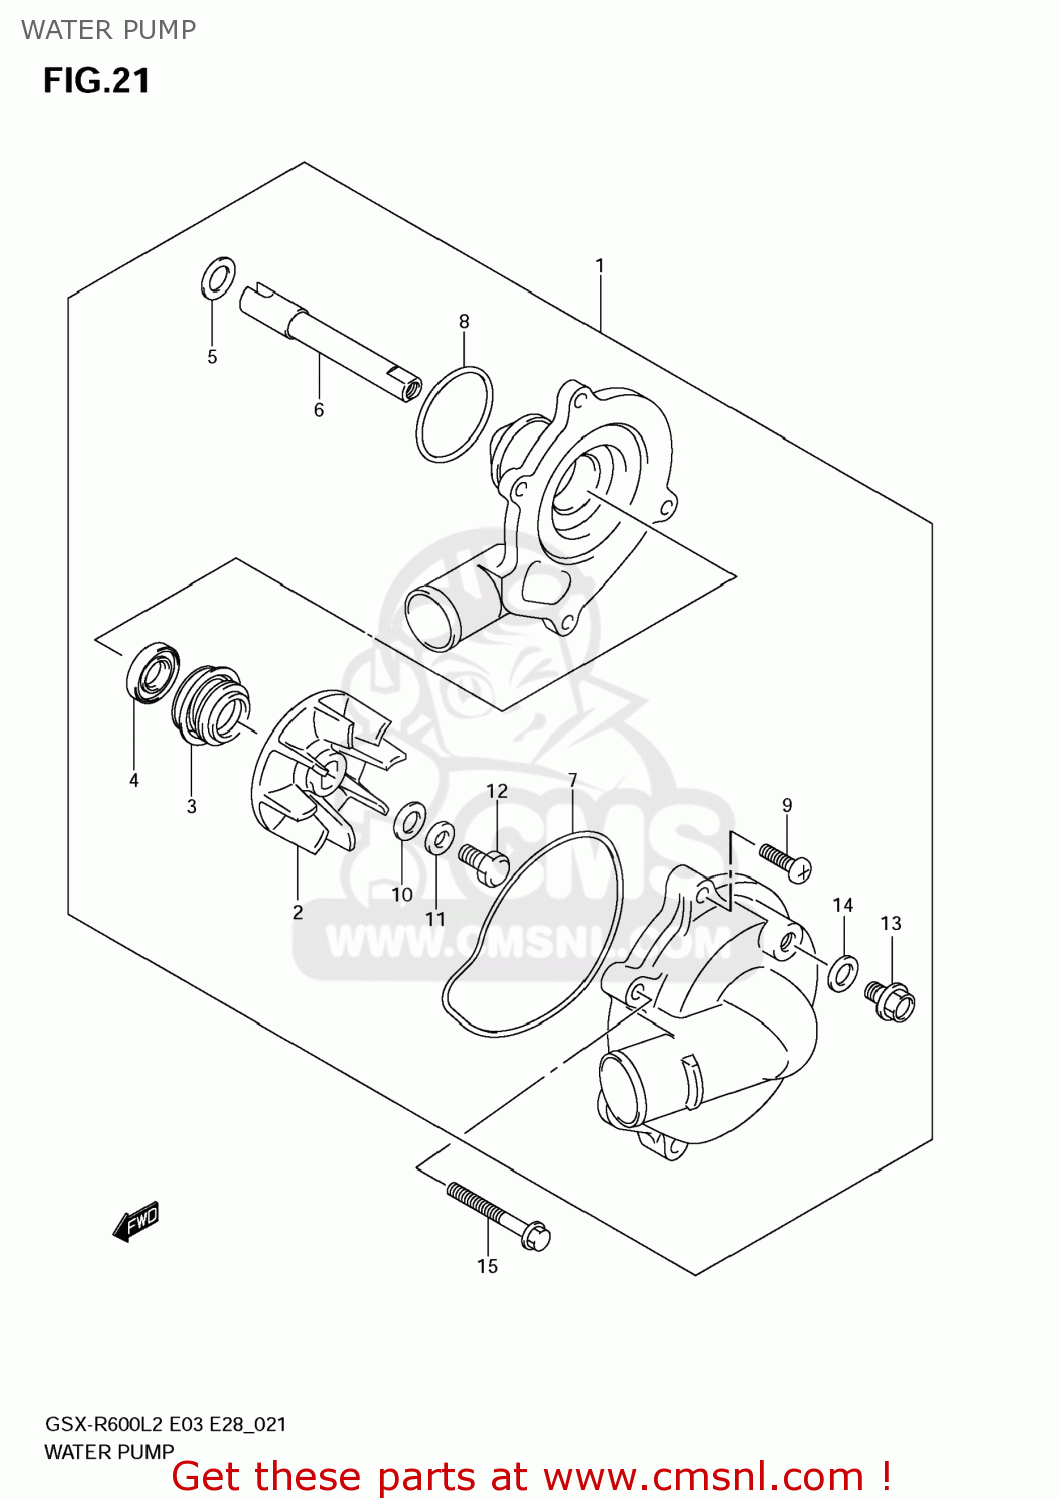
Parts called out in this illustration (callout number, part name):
1	PUMP ASSY,WATER
2	IMPELLER
3	SEAL,MECHANICAL
4	SEAL,OIL
5	WASHER
6	SHAFT
7	O RING
8	O RING,WATER PUMP HOLDER
9	SCREW
10	GASKET(6X15X2.2) (NAS)
11	WASHER
12	BOLT(6X13)
13	BOLT,DRAIN
14	GASKET(8.2X14X1) (NAS)
15	BOLT
